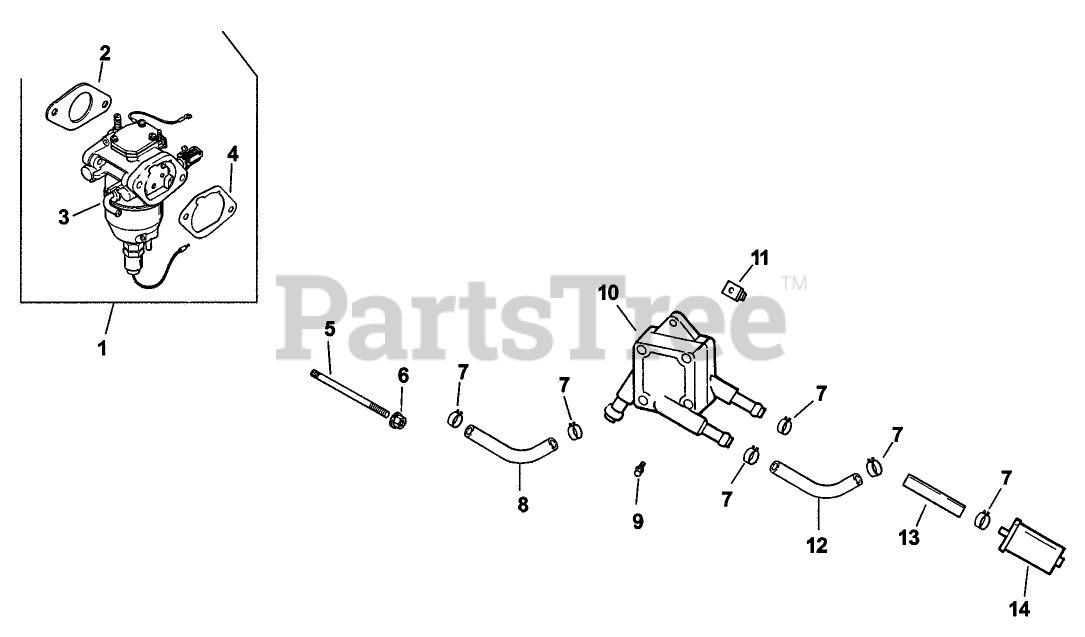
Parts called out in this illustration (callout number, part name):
1	Kit, carburetor with gaskets (Includes 2-4)
2	Gasket-carburetor
3	Carburetor assembly (For information only not available separately)
5	Stud
6	Nut-Hex Flange
7	Clamp
8	Line, fuel 10-1/2
9	SCREW-TAP (M6X1.7X18)
10	Pump, fuel-pulse
11	Nut-Plastic
12	Line, fuel 9"
13	Filter-Fuel
14	Filter-Fuel
